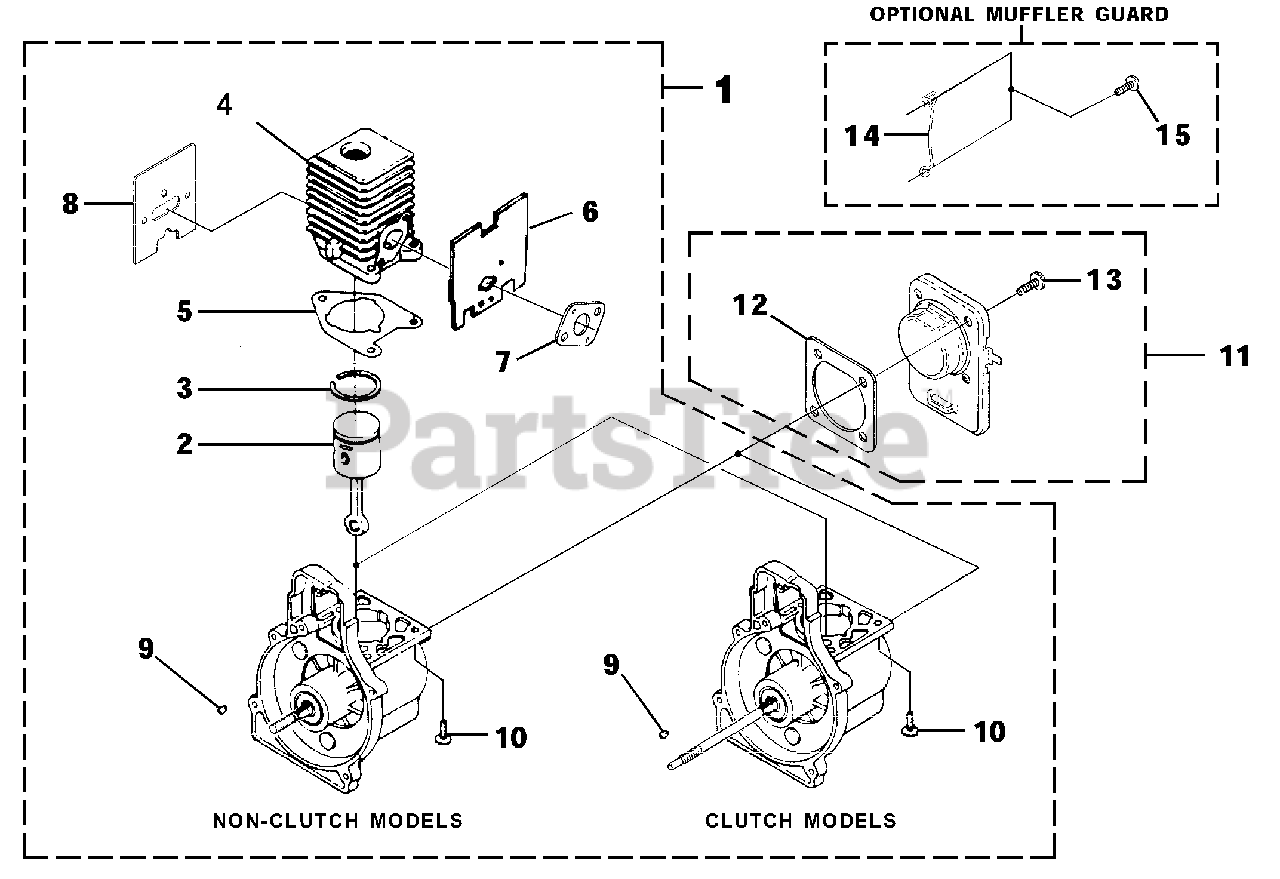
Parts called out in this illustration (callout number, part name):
1	SHORT BLOCK (Non-Clutch)
1	SHORT BLOCK (Clutch)
2	PISTON & ROD ASSY.
3	RING-Piston
4	CYLINDER ASSY.
5	GASKET-Cylinder
6	GASKET-Heat Dam
7	GASKET-Carburetor
8	GASKET-Muffler
9	KEY-Woodruff
10	SCREW-Sems (12-24 X 3/4")
11	CRANKCASE COVER ASSEMBLY
12	GASKET-Crankcase Cover
13	SCREW-Sems (10-24 X 1/2")
14	MUFFLER GUARD
15	SCREW-Thread Forming (10-14 X 1/2")
